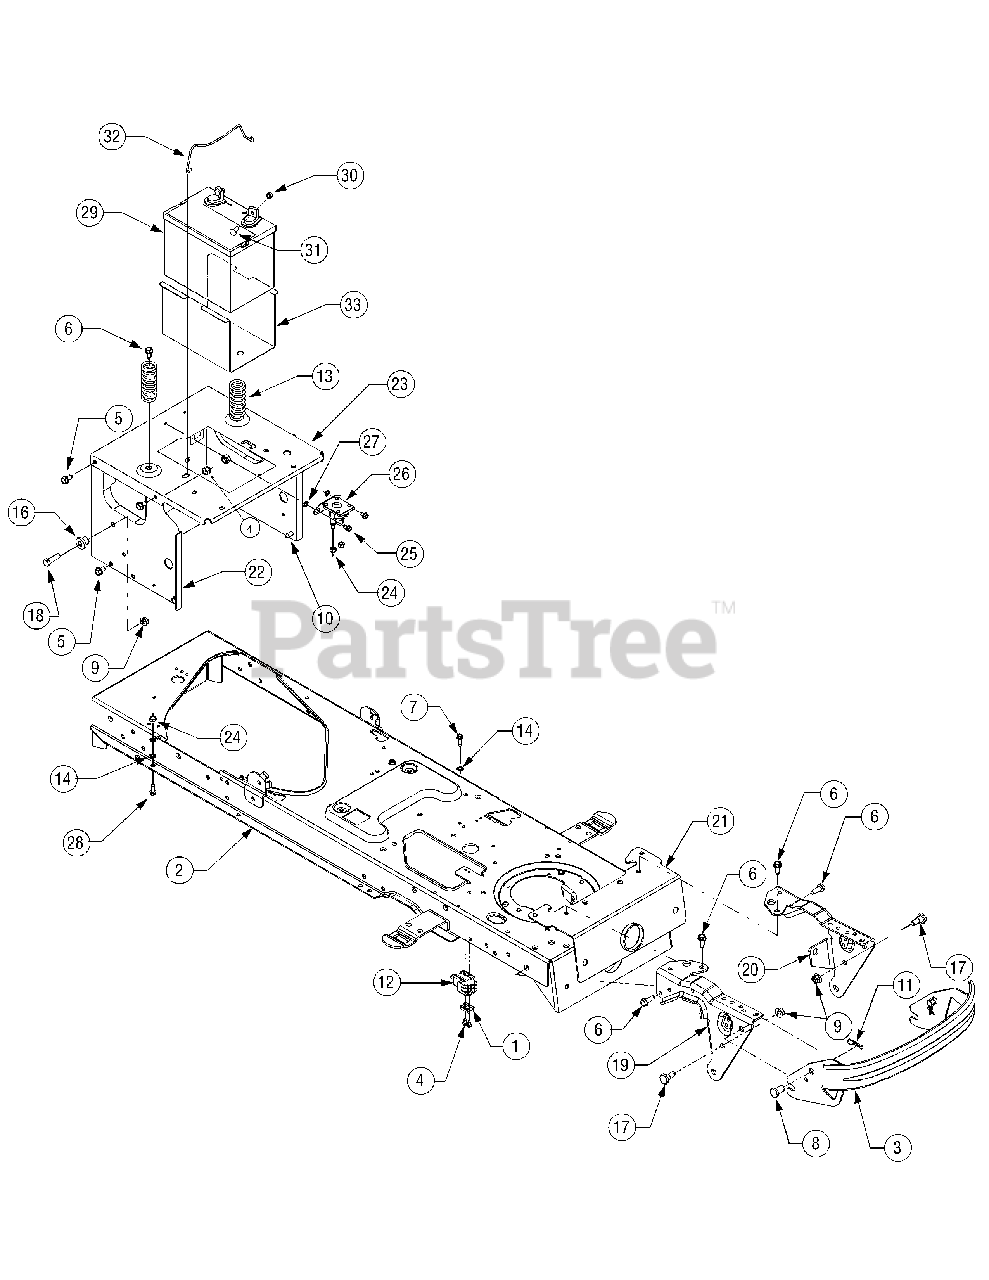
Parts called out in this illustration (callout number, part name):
1	Plate, Switch
4	Screw, Hex Washer, 10-16 x .5
5	Screw, Self-tapping, 5/16-18, 0.75
6	Screw, Self-tapping, 5/16-12, 0.75
7	Screw, Hex Washer, 1/4-20 x 0.625
8	Pin, Clevis, .50 Dia x .78 Lg
9	Nut, Nylon Lock, 3/8-16
10	Screw, Hex Wash. Tapp, 5/16-18 x .5
11	Pin, Internal Cotter
12	Switch, Interlock
13	Spring, Compression, 1.28 OD x 3.125
14	Washer, Lock, Ext 1/4
16	Shoulder Spacer
17	Shoulder Screw, 3/8-16
18	Hex Screw 3/8-16 x 1.25
24	Nut, Nylon Lock, 1/4-20
25	Screw, Self-tapping, 1/4-20, 0.500
26	Solenoid, 12V, 100 Amp
27	Washer, External Lock, 1/4
28	Screw, Hex. 1/4-20 x .75
29	Battery, 190 CCA
30	Nut, Sems, 1/4-20
31	Screw, Carriage, 1/4-20, .75,
32	Hold-down Rod, Battery
